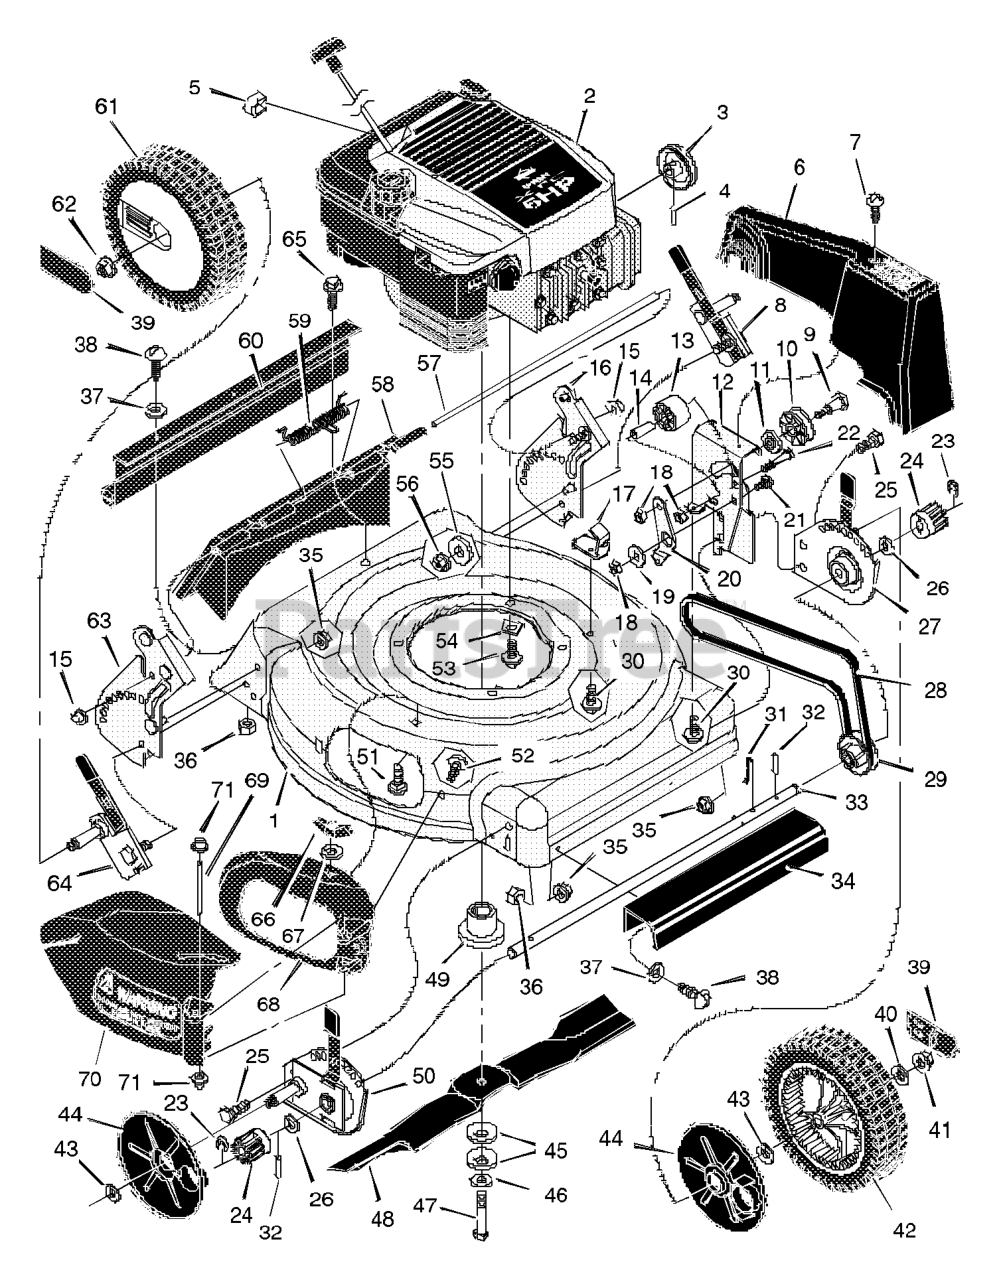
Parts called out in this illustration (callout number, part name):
1	Housing
2	Engine *
3	Pulley, Engine
4	Pin, Spring
5	Stop, Rope (Recoil - Start)
6	Cover, Belt
8	Adjuster, Left Height
9	Bolt, Shoulder
12	Bracket, Idler Support
13	Pulley, Idler
14	Bearing
15	Push On Cap
16	Bracket, Left Handle
17	Bracket, Cable
18	Nut, Hex
20	Arm, Idler
21	Bolt, Carriage
22	Bolt, Shoulder
23	E- Ring
24	Gear, Pinion
25	Bolt
27	Adjuster, Left Front Height
29	Pulley, Axle
31	Pin, Hair
32	Pin, Spring
34	Cover, Axle
35	Nut, Flange
36	Nut, Hex
39	Hub Cap
40	Washer
41	Nut, Flange
42	Wheel, Drive (Light Gray)
44	Cover, Dust
45	Washer, Belleville
49	Adapter, Blade
50	Adjuster, Right Front Height
51	Bolt, Carriage
53	Bolt, Engine
54	Support, Engine
55	Washer
56	Nut, Flange
57	Rod, Pivot
58	Door, Rear
60	Guard, Rear
61	Wheel, Rear (Light Gray)
62	Nut, Flange
63	Bracket, Right Handle
64	Adjuster, Right Height
66	Wingnut
67	Retainer, Push
69	Pin, Pivot
70	Deflector, Chute
71	Push On Cap
